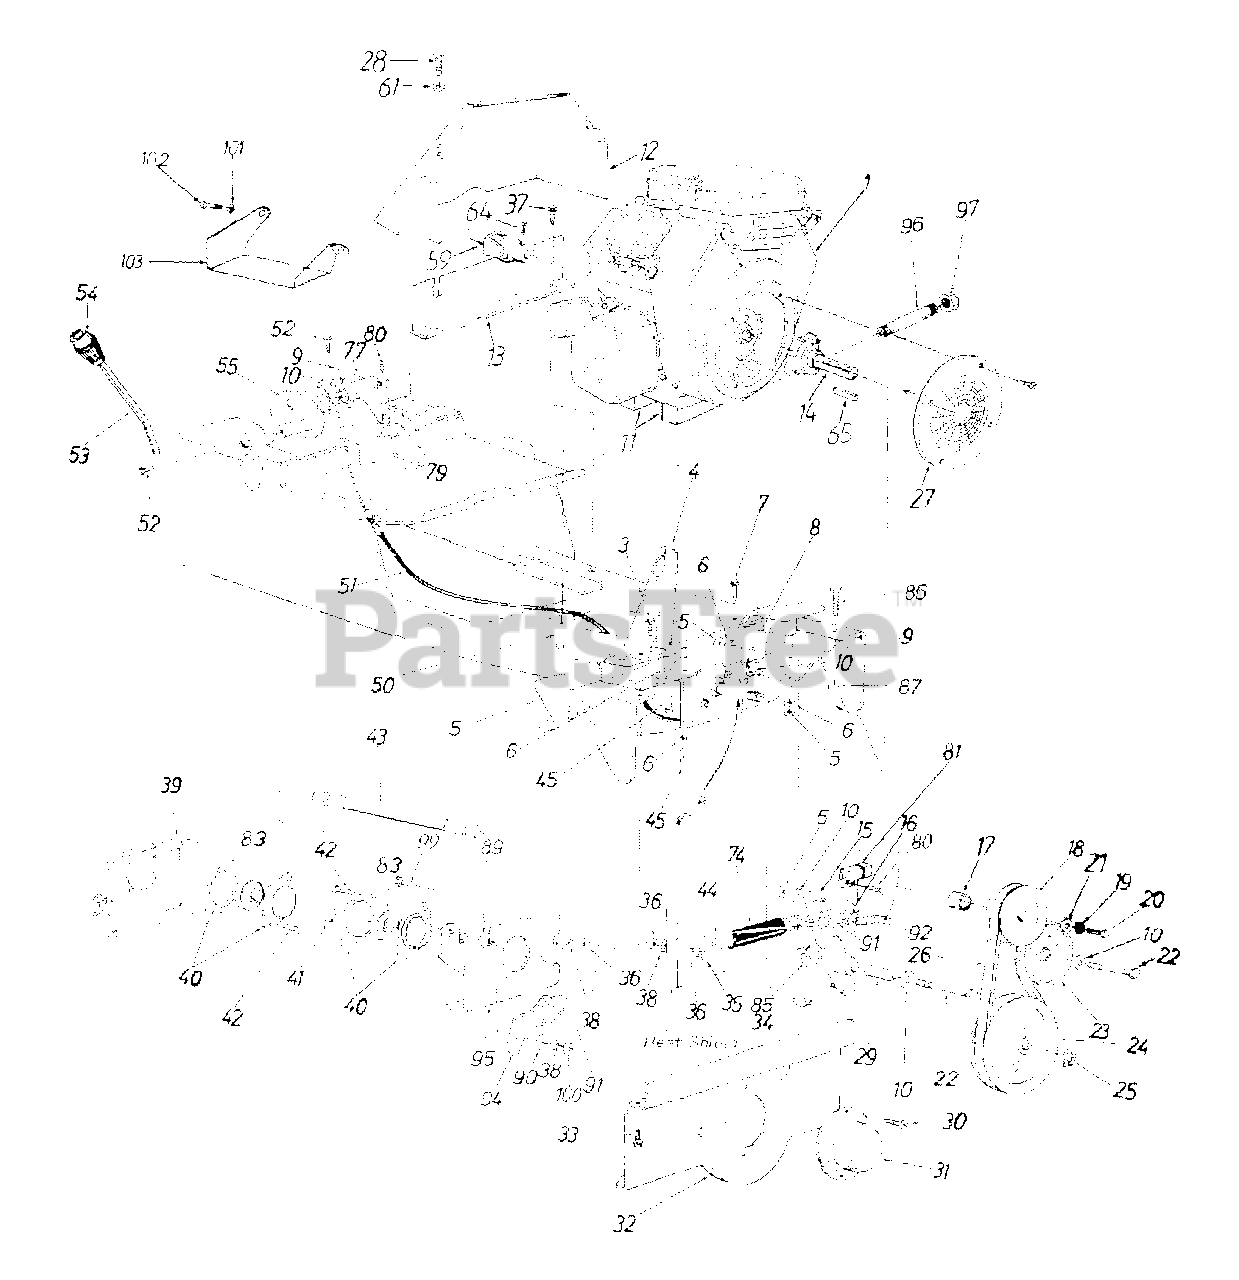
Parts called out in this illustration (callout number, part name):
1	Engine
3	Hex Wash. Hd. Self-Tap Scr. 1/4-20 x .75" Lg.
6	L-Wash. 3/8" I.D.
7	Hex Wash. Hd. Self-Tap Scr. 5/16-18 x .75" Lg.
10	Fl-Wash. .38" I.D. x 1.25" O.D. x .100" Thk.
11	Engine Spacer Bar
14	Crankshaft Ext.
15	PTO Idler Ass'y.
16	Idler Adapter
17	Pulley Spacer
18	Engine PTO-Pulley
19	L-Wash. 3/8" I.D.
20	Hex Bolt 3/8-24 x .88" Lg.
21	Fl-Wash. 3/8" I.D. x 1.37" O.D.
22	Hex Bolt 3/8-16 x 2.50" Lg.
23	Flat Idler Pulley
24	1/2" V-Pulley 7.00" O.D. (PTO)
25	Snap Ring
26	V-Belt (PTO)
27	Engine Screen
28	Hex Bolt M6-1.0 x 10 MM Lg.
29	Spacer .375" I.D. x .62" O.D. x 1.830" Lg.
30	Hex "B" Tap Scr. #10 x .50" Lg.
31	PTO Cup
34	#91 Hi-Pro Key
35	Hex Bolt 5/16-18 x 1.25" Lg.
36	Hex Nut 5/16-18 Thd.
37	Hex Wash. Hd. Tap Scr. 5/16-18 x .5" Lg.
38	L-Wash. 5/16" I.D.
39	PTO Brg. Retainer Brkt.
40	1.00" Dia. Brg. w/Flangette
41	Snap Ring
42	Carr. Bolt 5/16-18 x .75" Lg.
43	Spline Shaft
44	Extension Spring (PTO Clutch)
45	Hex Scr. 3/8-16 x 1.00" Lg.
50	Hex L-Wash. TT-Tap Scr. 3/8-16 Thd.
51	PTO Control Cable
52	Hex Wash. Hd. TT-Tap Scr. 1/4-20 x .5" Lg.
53	PTO Handle
54	Shift Knob
55	PTO Actuator Lever Ass'y.
59	Universal Drive Shaft Comp.
61	Fl-Wash. .281" I.D. x .5" O.D.
64	Set Scr. 5/16-18 x .38" Lg.
65	Sq. Key 1/4" x 2.00" Lg.
74	Spring Cover Tubing (PTO Clutch)
77	Solenoid
79	Circuit Breaker
80	Truss Mach. Scr. #10 x .50" Lg.
81	Safety Switch (PTO)
83	Ball Bearing
85	Bell-Wash. .39" I.D. x 1.13"
86	Hex Bolt 3/8-16 x 1.5" Lg.
87	Hex Cent. L-Nut 3/8-16 Thd.
89	Shoulder Spacer
90	Fl-Wash. .33" I.D. x 1.25" O.D.
91	PTO Brake Rod
92	Extension Spring 2.15" Lg.
94	Brake Ass'y.
95	PTO Brg. Retainer Brkt. Ass'y.
96	Pipe Nipple 3/8" x 5" Lg.
97	Oil Drain Cap
99	Hex Bolt 5/16-24 x .75" Lg.
100	Hex Nut 5/16-24 Thd.
101	L-Wash. 7/16" I.D.
102	Hex Bolt 7/16-14 x .75" Lg.
103	Heat Shield
